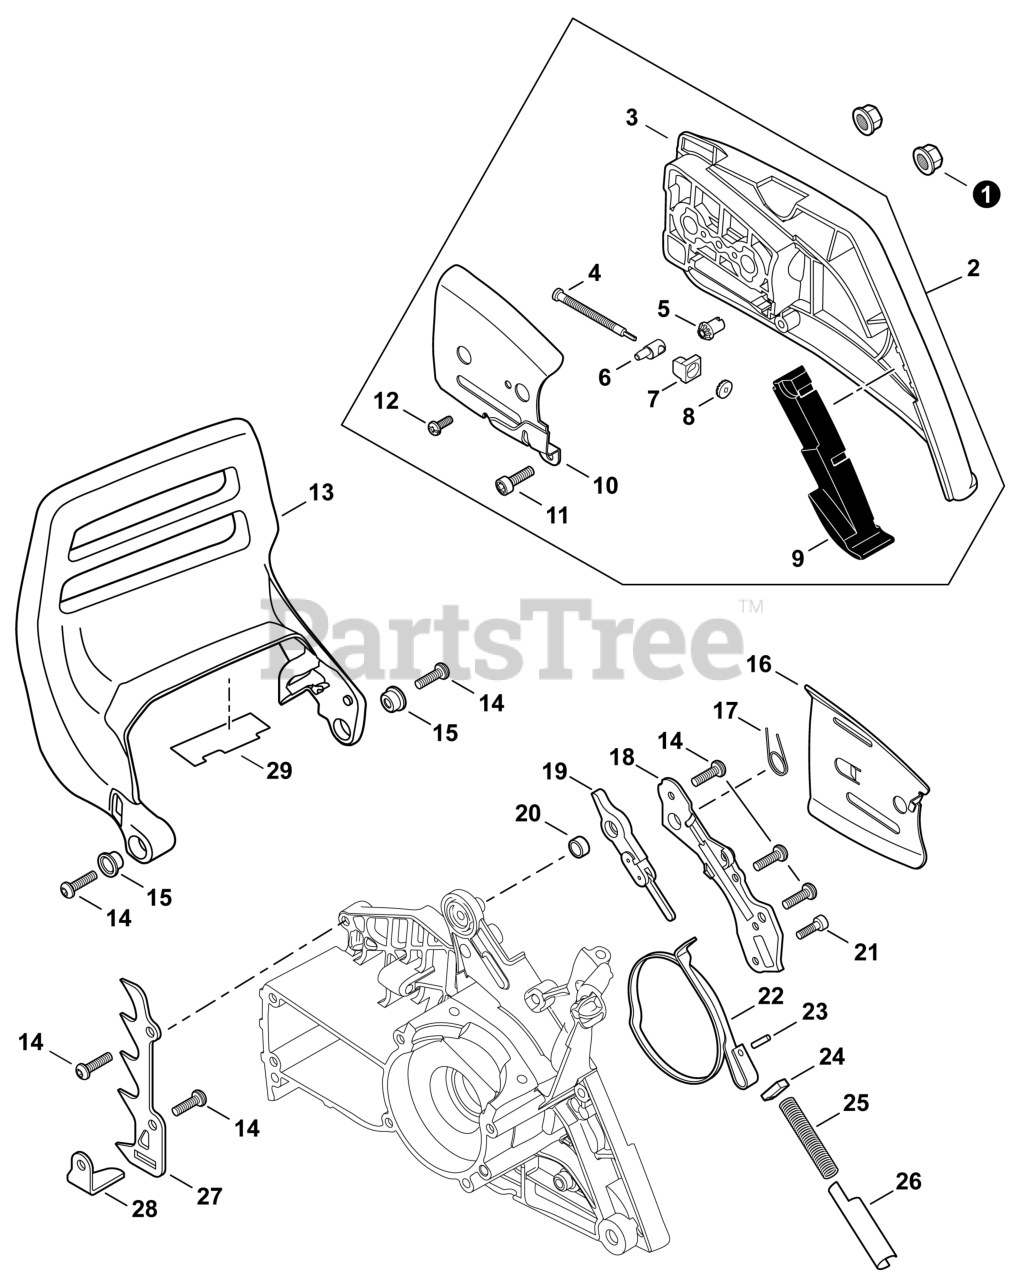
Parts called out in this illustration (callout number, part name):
1	NUT, FLANGE M8x1.25
2	GUARD KIT, SPROCKET
3	GUARD, SPROCKET
4	SCREW, CHAIN TENSION 63 MM
5	GEAR, BEVEL
6	TENSIONER, CHAIN
7	COLLAR 8
8	GEAR, BEVEL
9	CUSHION
10	PLATE, GUIDE - OUTER
11	BOLT, TORX 4x12
12	SCREW 3x6
13	LEVER, BRAKE
14	BOLT, TORX 5x16
15	COLLAR 10
16	PLATE, GUIDE - INNER
17	SPRING, TORSION
18	COVER, BRAKE
19	CONNECTOR, BRAKE
20	SPACER 12x10xT: 1.0
21	BOLT, TORX 4x12
22	BAND, BRAKE
23	PIN, SPRING 3x9.8
25	SPRING, COMPRESSION 12x70.5
26	PLATE, SIDE
27	SPIKE, BUMPER
28	CATCHER, CHAIN
29	SHIELD, HEAT 75x27x0.15
